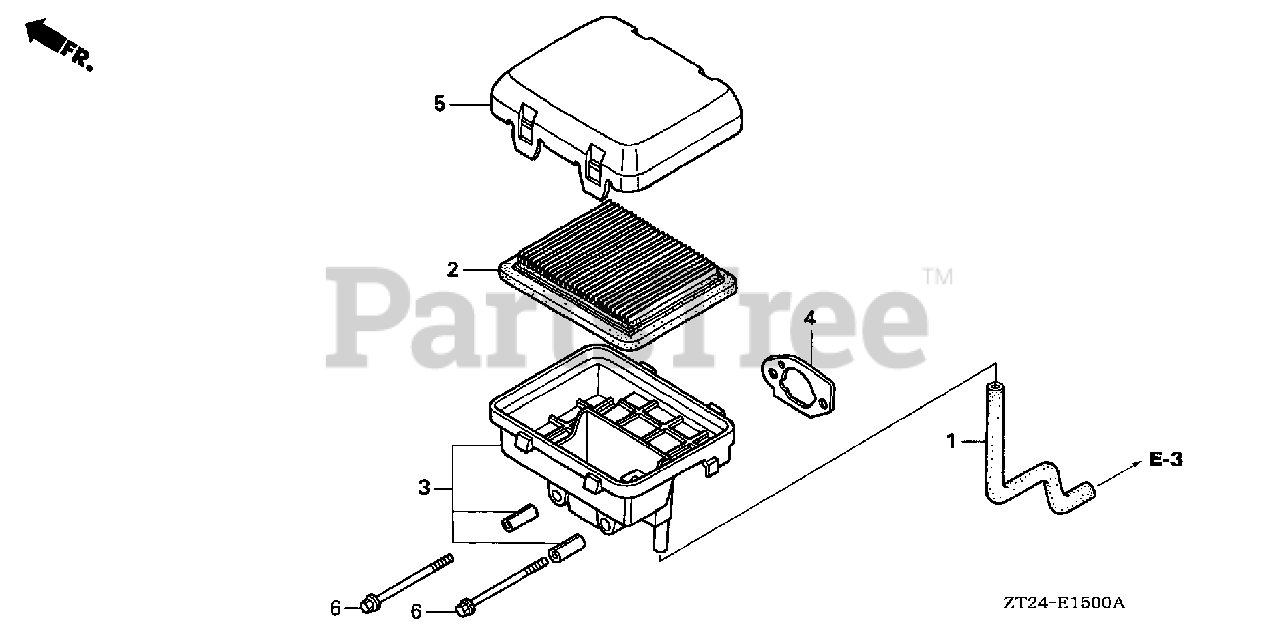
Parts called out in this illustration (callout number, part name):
1	TUBE, BREATHER
2	ELEMENT, AIR CLEANER
3	HOUSING, AIR CLEANER
4	GASKET, AIR CLEANER
5	COVER, AIR CLEANER
6	BOLT, FLANGE (6X112) (CT200)
